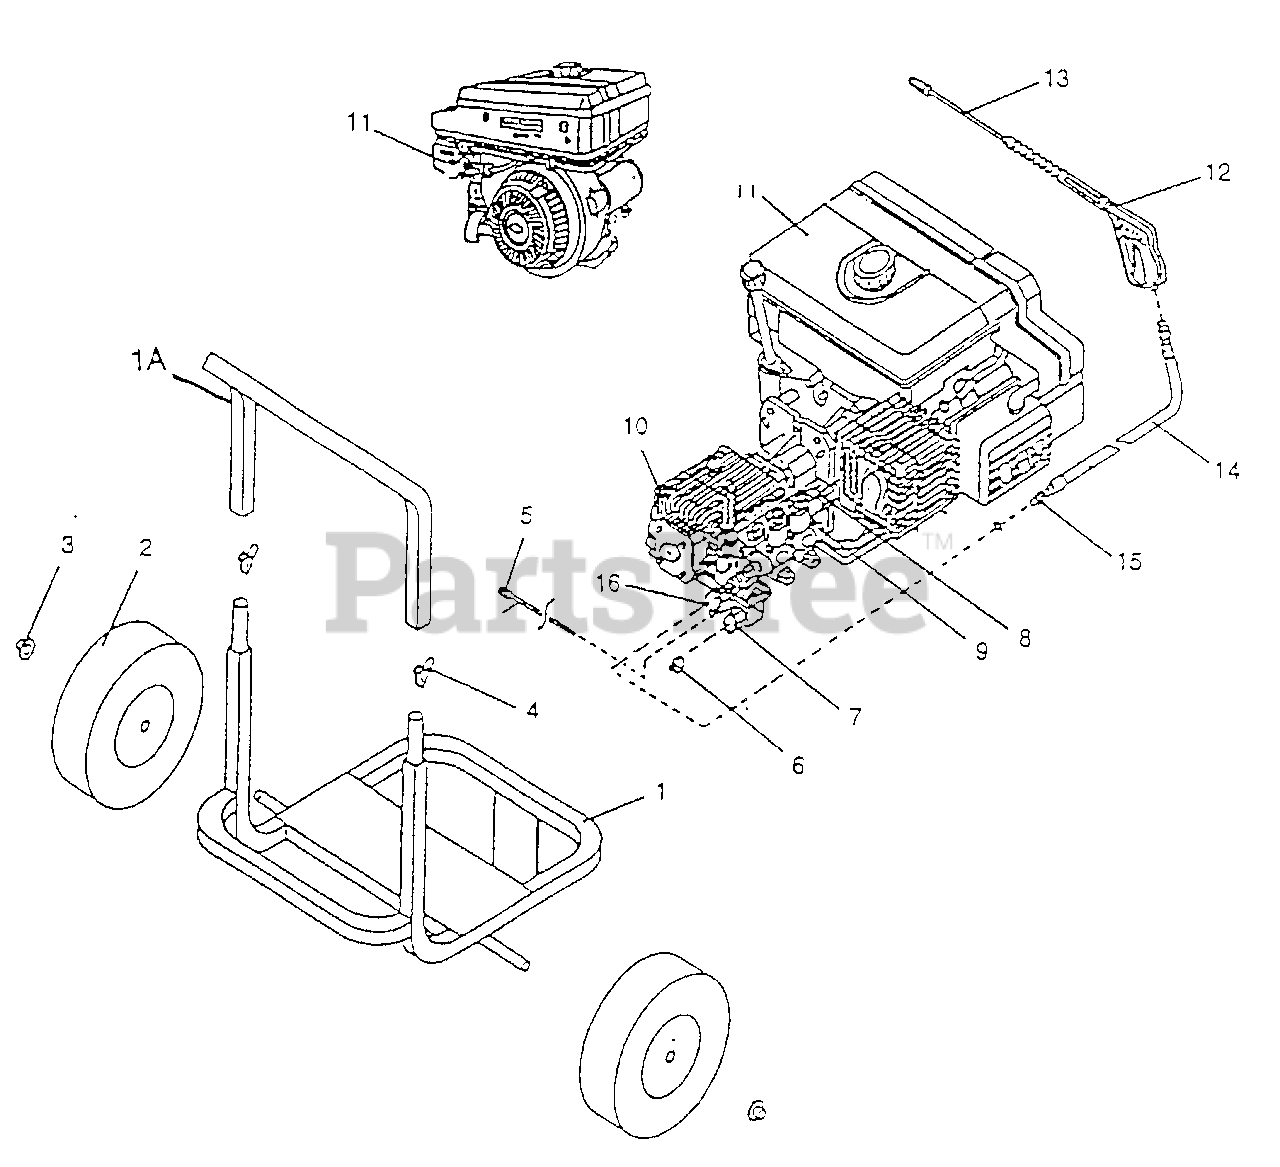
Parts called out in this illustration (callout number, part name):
1A	Handle Bar
2	Hard Rubber Tires
3	Hub Caps
4	Hub Caps
5	Nylon Braid Hose with Screen
6	Hose Screen
7	Garden Hose Adapter
8	Relief Valve
9	General Pump Thermo Valve
10	General Pump
11	9 HP Briggs & Stratton Engine
12	9 HP Wand
13	Hi/Low Nozzle
14	Hose R1-3/8" x 50'
15	3/8" Female Q.C. Plug
16	Female Q.C. Socket
